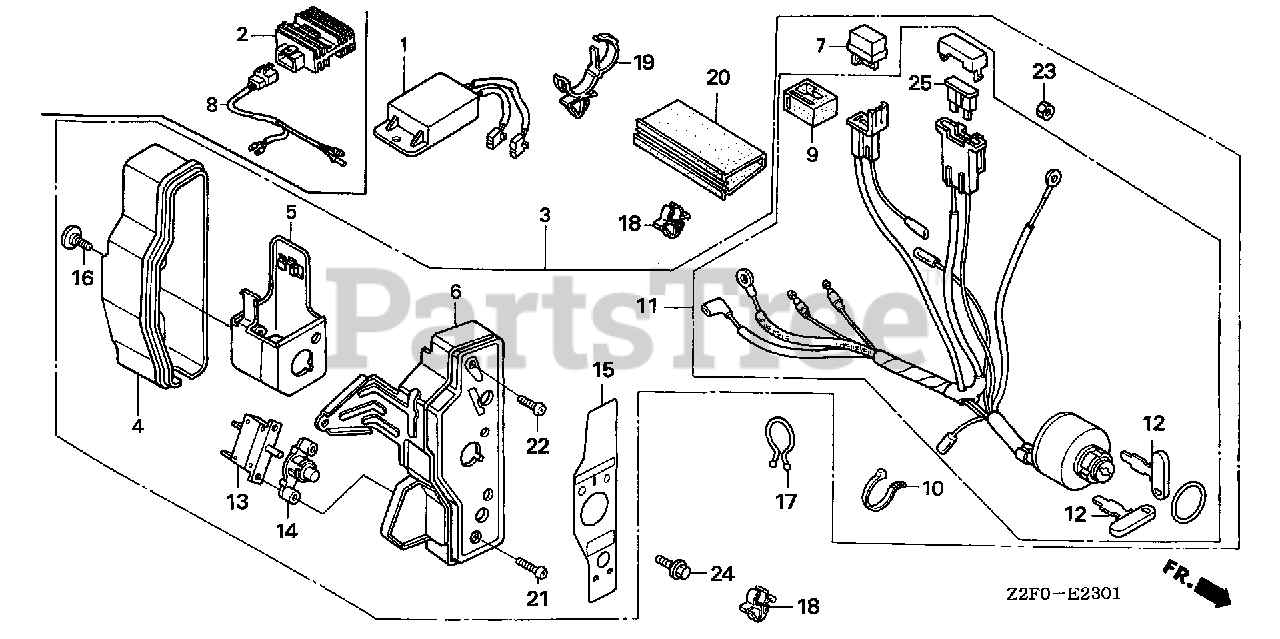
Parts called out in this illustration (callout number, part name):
1	RECTIFIER, REGULATOR
2	RECTIFIER ASSY., REGULATOR (10A)
3	BOX ASSY., CONTROL *NH1* (INTERNAL) (BLACK)
3	BOX ASSY., CONTROL *R280* (INTERNAL) (POWER RED)
3	BOX ASSY., CONTROL *NH1* (EXTERNAL) (BLACK)
3	BOX ASSY., CONTROL *R280* (EXTERNAL) (POWER RED)
4	CASE, CONTROL
5	BRACKET, CASE MOUNTING
6	PANEL, CONTROL *NH1* (BLACK)
6	PANEL, CONTROL *R280* (POWER RED)
7	RECTIFIER ASSY., SILICON (SHINDENGEN)
8	SUB-WIRE HARNESS ASSY.
9	SUSPENSION, CONNECTOR
10	BAND
11	SWITCH ASSY., COMBINATION
12	KEY (HONDALOCK)
13	PROTECTOR, CIRCUIT (1.0A)
14	LENS ASSY., PROTECTOR
15	PANEL, CONTROL BOX (INTERNAL)
16	SCREW, SPECIAL (6X12)
17	CLIP, PURSE LOCK
18	CLIP, CORD
19	STRAP, WIRE HARNESS (25MM) (BLACK)
20	TUBE, FASTENER (30MM)
21	SCREW, PAN (3X12)
22	SCREW, PAN (4X12)
23	NUT, HEX. (4MM) (SOURCE: VINTAGE PARTS INC.)
24	BOLT, FLANGE (6X10)
25	FUSE, BLADE (5A)
